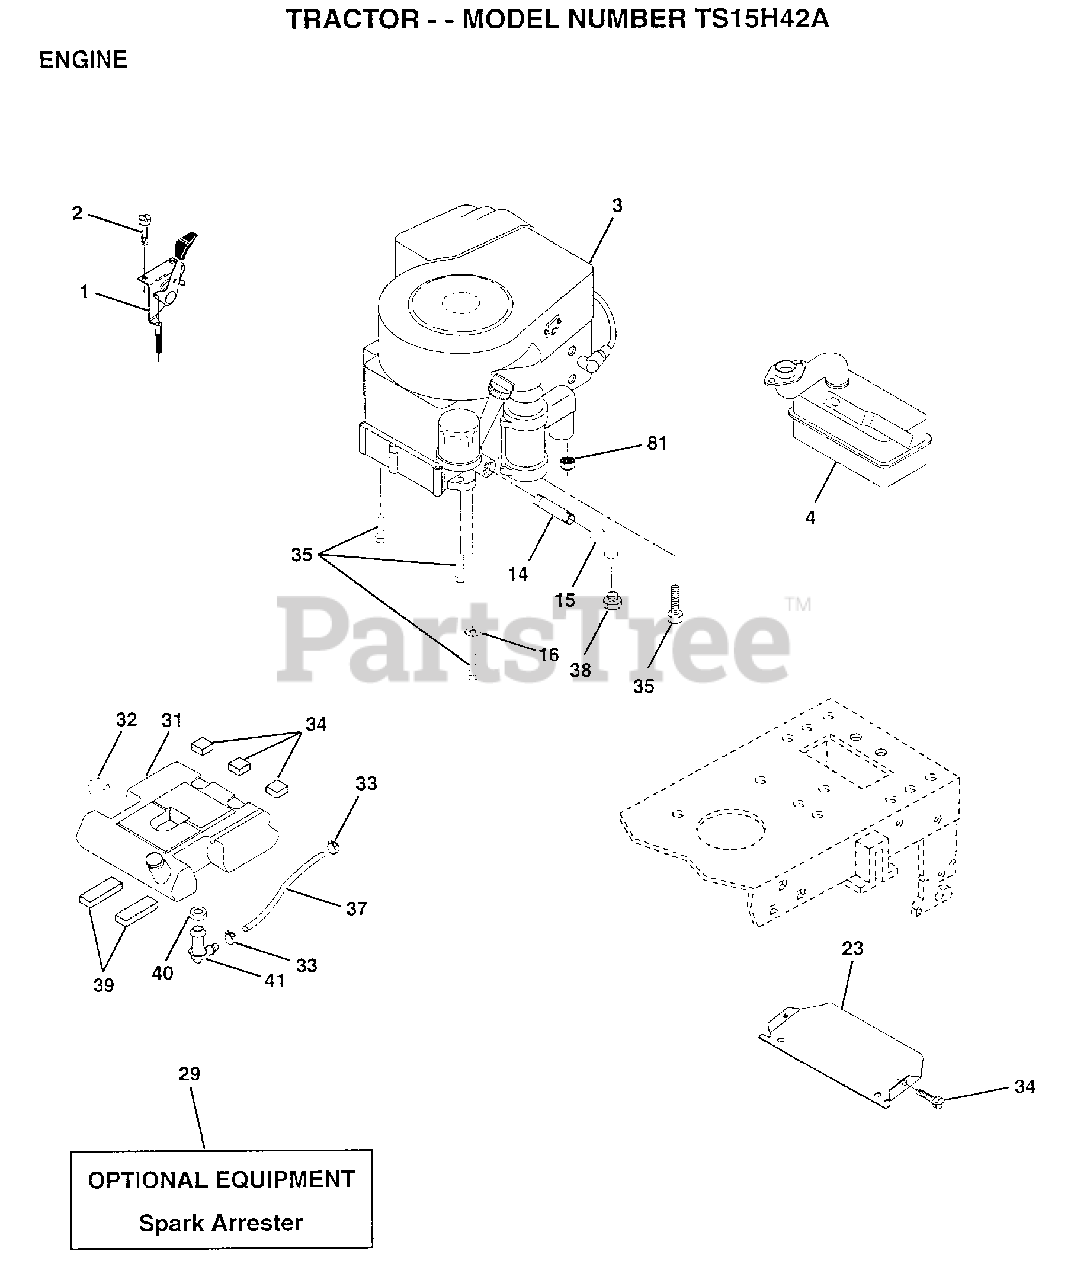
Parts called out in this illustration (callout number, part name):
1	"CONTROL,THROTTLE"
2	SCREW LT
4	MUFFLER EXHAUST
14	PIPE NIPPLE
15	ELBOW
16	LOCKWASHER
31	TANK FUEL REAR
32	CAP ASM FUEL
33	HOSE CLAMP
34	PAD-SPACER LT
35	SCREW
37	FUEL LINE T
39	PAD IDLER TI
40	BUSHING OUTLET T
41	STEM.TANK.FUEL
81	NUT
